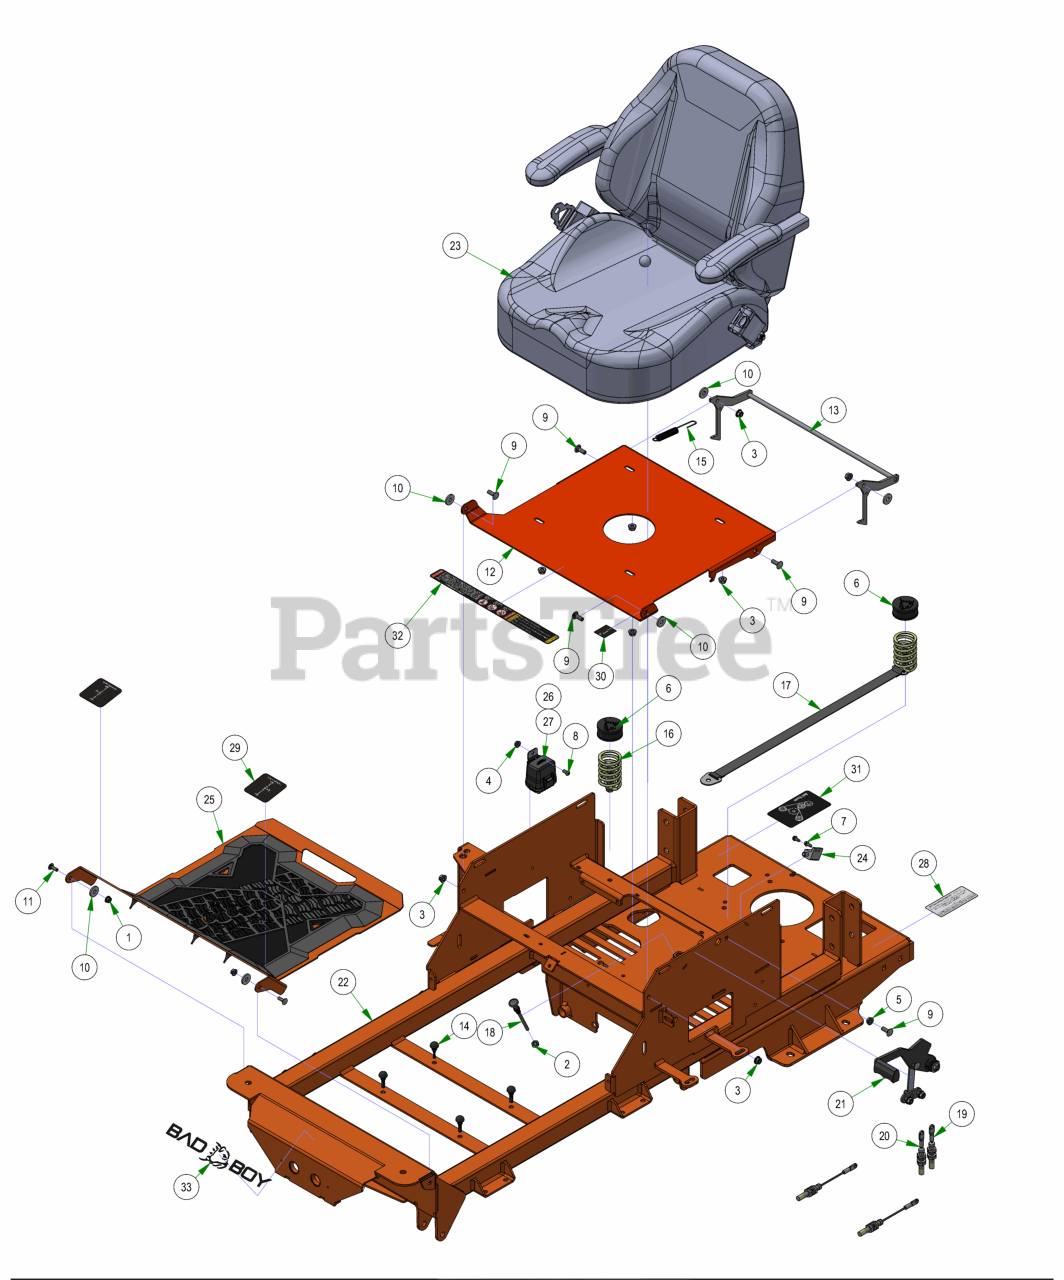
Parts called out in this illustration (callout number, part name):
1	1/4-20 NYL INSERT FLANGE LOCKNUT ZINC
2	3/8-24 HEX NUT ZINC YELLOW
3	5/16-18 NYLON INSERT FLANGE LOCKNUT ZINC
4	1/4-20 HEX SERRATED FLANGE NUT HARD/ZINC
5	5/16-18 HEX SERRATED FLANGE NUT HARD/ZINC
6	Spring Cap Cover
7	12-24 X 1/2 HEX WASHER UNLSOT F TCS ZINC
8	1/4-20 X 1/2 BUTTON SOCKET CAP SCREW 18-8 STAINLESS STEEL
9	5/16-18 X 7/8 CARRIAGE BOLT ZINC
10	.360 ID X .983 OD X .120 THICK FLAT WASHER NYLON
11	1/4-20 X 3/4 CARRIAGE BOLT (GR.5) ZINC
12	Seat Plate 2016
13	Seat Latch Rod Assembly
14	2023 Floor Board Rubber Bumper
15	Brake Spring
16	Seat Spring Assembly
17	2022 Mav/HD seat spring assembly with strap
19	2021 Load Balanced Brake Cable 1
20	2021 Load Balanced Brake Cable 2
21	2021 Load Balanced Brake Handle Assembly
22	2025 Maverick Frame
23	2024 Maverick Digital Seat
24	Safety Switch
25	2025 ZT/Mav/HD Floorboard Assembly
26	2024 Wiring Harness with Clips
27	2025 Wiring Harness with Clips and Lights
28	2025 EPA Build Date Punch Decal
29	2018 Maverick/2021 ZT Anti-Skid Steering Control Decals
30	2018 MZ/Magnum/ZT/MAV/Comp Out Brake Decal
31	Maverick Pump Belt Decal
32	Outlaw Warning Decal
33	Flying Bulldog Front Bumper Decal
